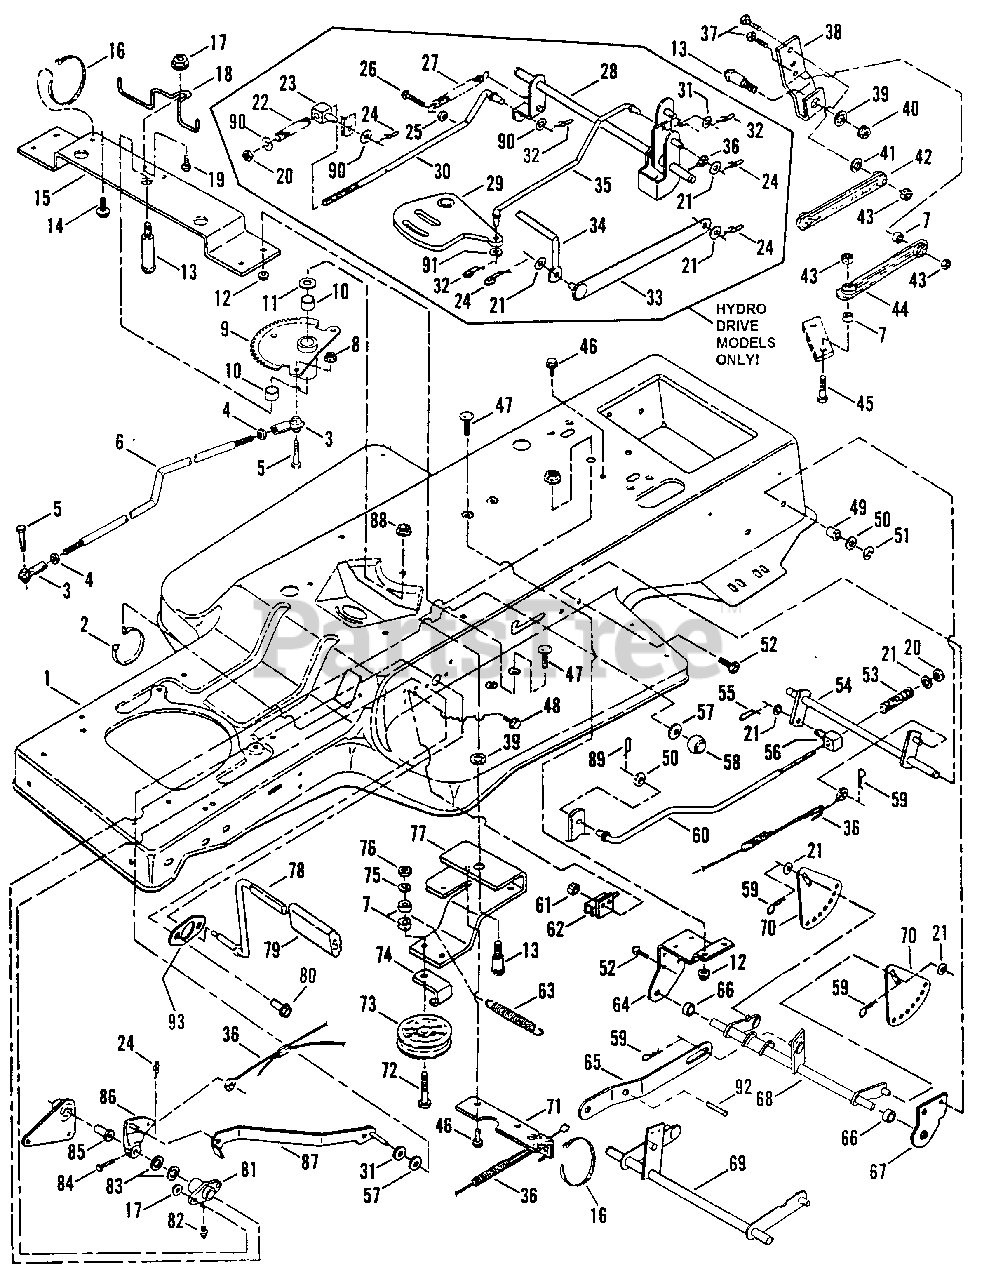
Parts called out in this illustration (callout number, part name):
1	FRAME, Tractor
2	TIE, Wire
3	BALL JOINT, 3/8-24
4	NUT, 3/8-24 Hex Jam
5	SCREW, 3/8-24 x 1-1/4" Hex Head Cap, Grade 5
6	LINK, Drag
7	SPACER
8	NUT, 3/8-16 Hex Flange Lock
9	ASSEMBLY, Sector Gear
10	BEARING, Sector Gear
11	WASHER, 3/4 Thrust
12	NUT, 1/4-20 Hex Fl. Lock, Gr. 5
13	BOLT, 1/2-13 x 2" Shoulder
14	SCREW, #10-24 x 1/2" Hex Washer Self-Tap (Torx)
15	BRACE, Sector Gear
16	TIE, Cable
17	NUT, 5/16-18 Hex Fl. Lock, Gr. 5
18	GUIDE, Drive Belt
19	BOLT, 5/16-18 x 3/4" Hex Flange Lock, Grade 5
20	NUT, 3/8-16 Hex Nyloc
21	WASHER, 3/8" Flat
22	SPRING, Brake
23	SWIVEL, Inline Brake
24	PIN, 3/8" Cotter Self-Lock
25	NUT, 5/16-18 Hex Ctr. Lock, Grade 5
26	SCREW, 5/16-18 x 1-1/4" Self-Tap.
27	SPRING
28	ARM, Brake
29	ARM, Transmission Speed Control
30	ROD, Brake
31	WASHER, 5/16 Flat
32	PIN, 5/16 Cotter, Self-Locking
33	LINK, Shift
34	ASSEMBLY, Shift Lever (Lower)
35	LINK, Speed
36	ASSEMBLY, Clutch/Brake Cable
37	SCREW, 3/8-16 x 1-1/4", Gr. 5
38	BELLCRANK, Shift Lever
39	WASHER, 1/2 Internal Tooth Lk.
40	NUT, 1/2-13 Hex Fl. Lock Gr. 5
41	WASHER, 3/8 Split Lock
42	LINK, Shift Lever
43	NUT, 3/8-16 Hex Ctr. Lock, Gr. 5
44	LINK, Shift Lever (Twisted)
45	SCREW, 3/8-16 x 1-1/2", Gr. 5
46	SCREW, 5/16-18 x 5/8" Self-Tap
47	BOLT, 1/4-20 x 5/8" Carriage
48	SCREW, #10-32 x 5/8", Grade 5
49	BEARING, Nylon
50	WASHER, 1/2 Flat
51	RING, 1/2" External Retaining
52	SCREW, 5/16-18 x 5/8" Truss Hd.
53	SPRING, Brake
54	PIVOT, Brake
55	COTTER-PIN, 1/16" x 1.42" Self-Locking
56	SWIVEL, Brake Link
57	WASHER, 5/16 Nylon
58	KNOB, Push/Pull
59	PIN, 3/32 x 1 1/2" Hair
60	ROD, Brake
61	NUT, #10-32 Hex Nyloc
62	SWITCH
63	SPRING
64	BRACKET, Rear Lift/PTO Lever
65	LINK, Lift
67	BRACKET, Deck Hang Pivot
68	ARM, Rear Lift
69	ARM, Rear Lift
70	PLATE, Lift Sector
71	EXTENSION, Idler Arm
72	SCREW, 3/8-16 x 2-1/4" Hex Head Cap, Grade 5
73	PULLEY
74	GUIDE, Pulley
75	WASHER, 3/8 Split Lock
76	NUT, 3/8-16 Hex, Grade 5
77	ARM, Idler (Traction Drive)
78	PEDAL, Park Brake
79	PAD, Pedal
80	SCREW, 5/16-18 x 7/8 Truss Head (Torx)
81	ASSEMBLY, Foot Shaft Pivot
82	FITTING, Lube
83	WASHER, 5/8 Flat
84	PIN, 3/16 x 1-1/2" Clevis
85	BEARING, Flange
86	ASSEMBLY, Clutch Brake Arm
87	LATCH, Park Brake
88	NUT, 1/2-13 Hex Center Lock, Gr. 5
89	PIN, 1/2 Cotter, Self-Locking
90	WASHER, 3/8" Flat
91	WASHER, 11/32 I.D. x 7/8" O.D., Grade 5
92	PIN, 1/4 x 1-1/2" Roll
93	WASHER, Pivot - Stiffener
